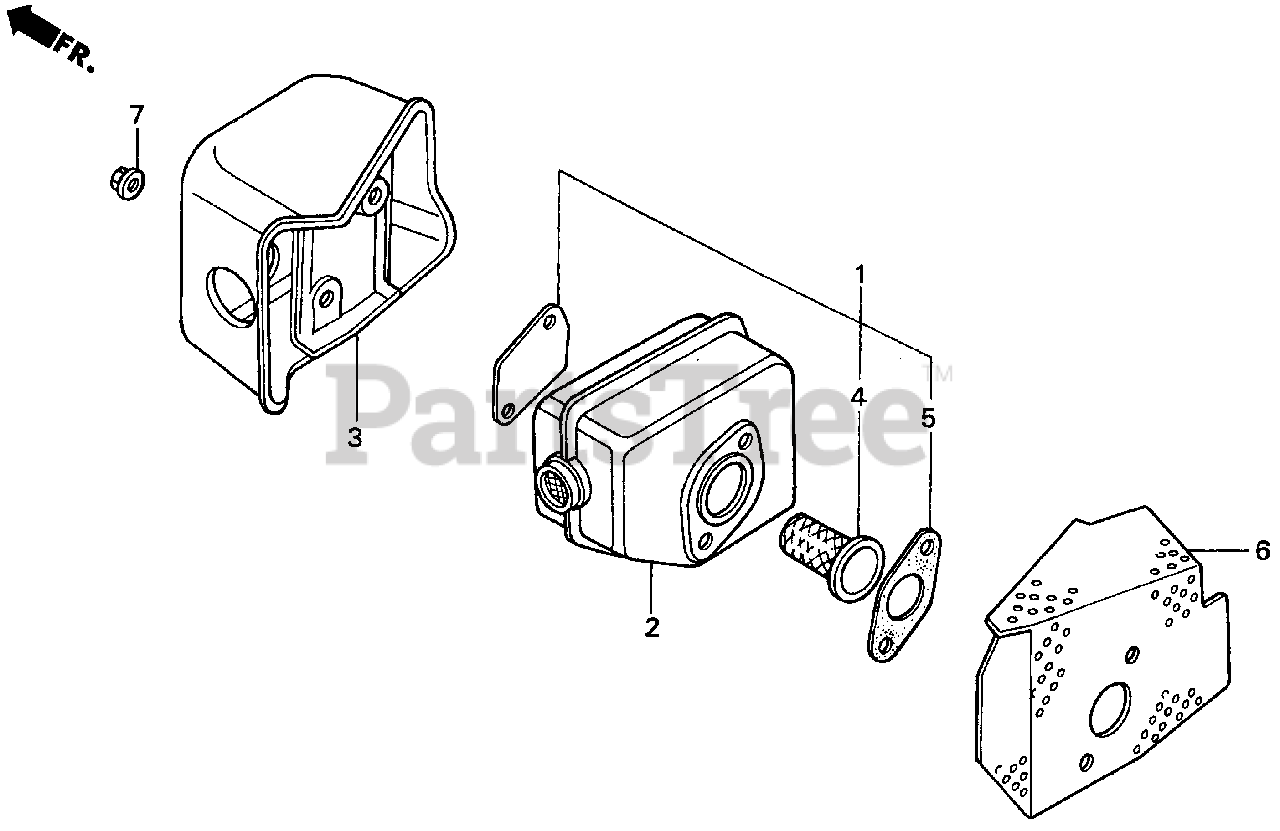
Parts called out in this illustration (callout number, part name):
1	ARRESTER KIT, SPARK
2	MUFFLER
3	PROTECTOR, MUFFLER
4	ARRESTER KIT, SPARK
5	GASKET, MUFFLER
6	GASKET, MUFFLER
7	NUT, SELF-LOCK (6MM)
